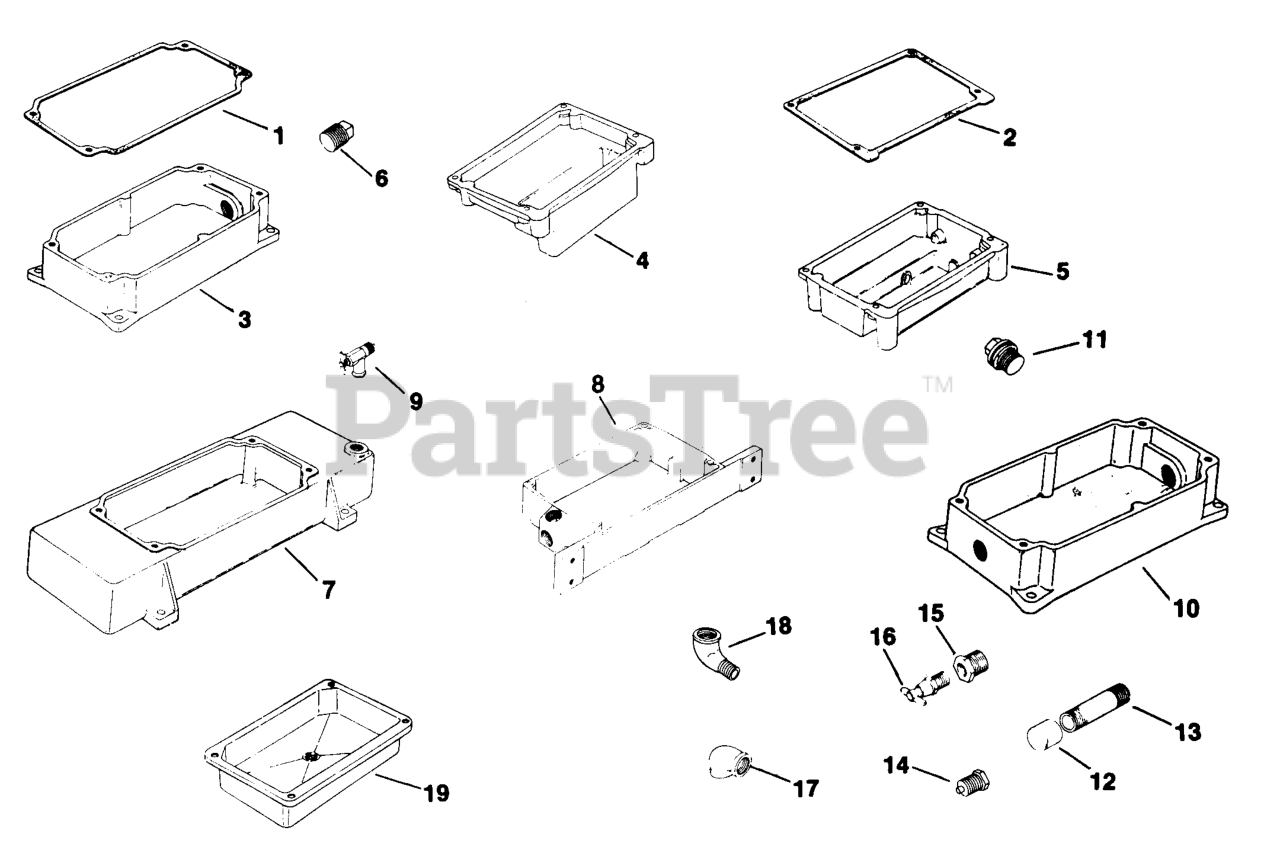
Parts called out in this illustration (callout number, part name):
5	KIT, OIL PAN
5	PAN
6	PLUG,PIPE 1/4 NPTF SQUARE HD USE 25 139 53-S
11	PLUG USE 25 139 64-S
